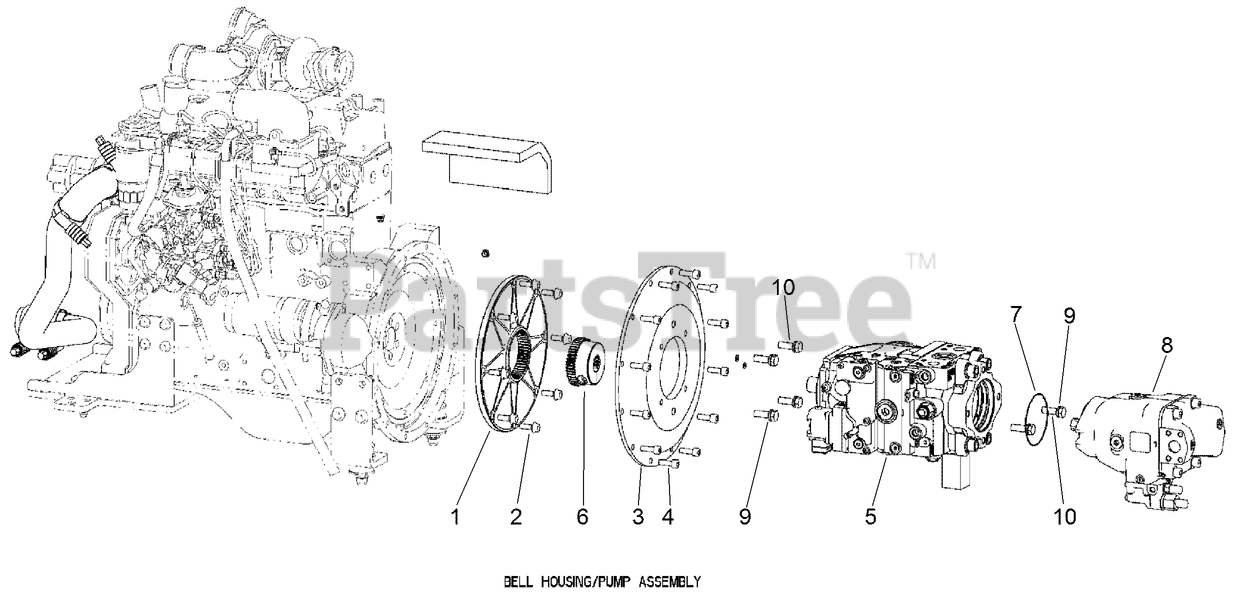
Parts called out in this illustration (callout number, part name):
1	COUPLING-DRIVE
2	SCREW-HH
3	MOUNT - Pump
4	SCREW-HSH
5	HYD HYDROSTAT PUMP ASM
6	HUB-STEEL
7	O-RING - .062 x 4.00 in Class 5
8	HYD LOAD SENSE PISTON PUMP ASM
9	WASHER-Spring Lock Reg 1/2 ZND
10	SCREW-HH
